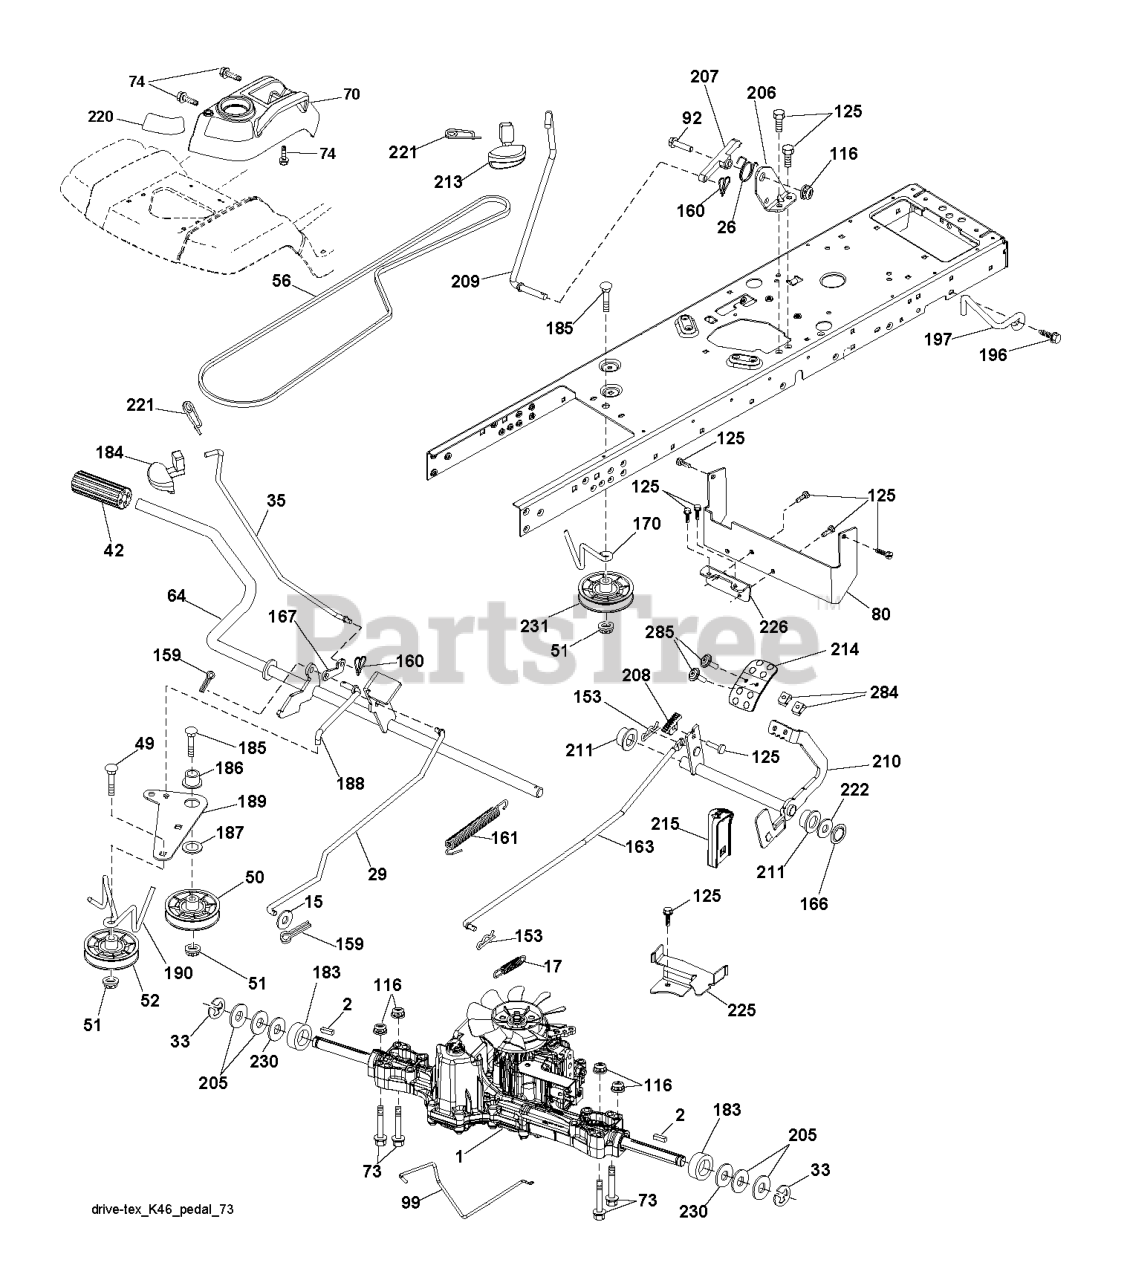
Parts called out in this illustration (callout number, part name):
2	SQUARE KEY
15	WASHER
17	SPRING.BRAKE.K46.GREEN
26	SPRING.RETURN.CRUISE
29	ROD.BRAKE.K46
35	ROD.BRAKE.PARKING.GT.H
42	PEDAL COVER T
50	IDLER.FLAT.910.OFFSET
51	NUT LOCK FLG 3/8-16 UNC
52	IDLER.V-GROOVE.910.OFFSET
56	V-BELT.MOWER.92.40.42/K46
64	SHAFT.ASM.PEDAL.BRK.CNTR
70	RP CONSOLE.ASM.PCH.W/TB
73	BOLT HEX 5/16-18 GR 5
74	SCREW.HI-LO.CONSOLE
80	STRAP TORQUE
92	BOLT
99	ROD.SPRING.BYPASS.K46.LT.Z
116	NUT LOCK HEX FLANGE 5/16-18
125	SCREW
153	RETAINER M
159	COTTER PIN
160	RETAINER CLIP
161	SPRING, RETURN LT
163	ROD.CONTROL.PEDAL.K46
166	NUT.PUSH.625
167	LATCH.BRAKE.SPRING
170	KEEPER.CENTER SPAN.1.688
183	SPACER AXLE
184	HANDLE.PARKG.BRK.HUSQ X667
186	SPACER.RETAINER
187	WASHER 12/32X2X10GA
188	RP.LINK.CLUTCH.GROUND.DRIVE
189	BELLCRANK.GROUND.DRIVE.TEX.
190	KEEPER.BELLCRANK.DRIVE
196	SCREW 3/8-16X1
197	LINK.CLUTCH.ANIT-ROTAT
206	BRKT.MOUNT.LATCH.CRUIS
207	LATCH.CONTROL.CRUISE
208	GEAR.SECTOR.CONTROL.CR
209	ROD.CONTROL.CRUISE.GT.
210	ROCKER.ASM.PEDAL.CONTR
211	BEARING.NYLON
213	KNOB.CONTROL.CRUSIE.HU
214	PEDAL.FORWARD.HUSQVARNA.DEALER
215	PEDAL.REVERSE.TEX.GT.4
220	REFLECTOR.RH.TEX GT
221	RETAINER.SPRING.CLIP.H
222	WASHER 21/32 X 1-1/4 X 10 GA.
225	KEEPER.BELT.TRANSAXLE.K46
226	BRACKET.MOUNT.TORQUE.K46.TLT
230	WASHER.HARDENED
231	IDLER.V-GROOVE.1.688.OFFSET
284	NUT.U-CHNL.1/4-20.550DP.350PNL
285	SCREW.PHD.1/4-20.BOX DRVE
